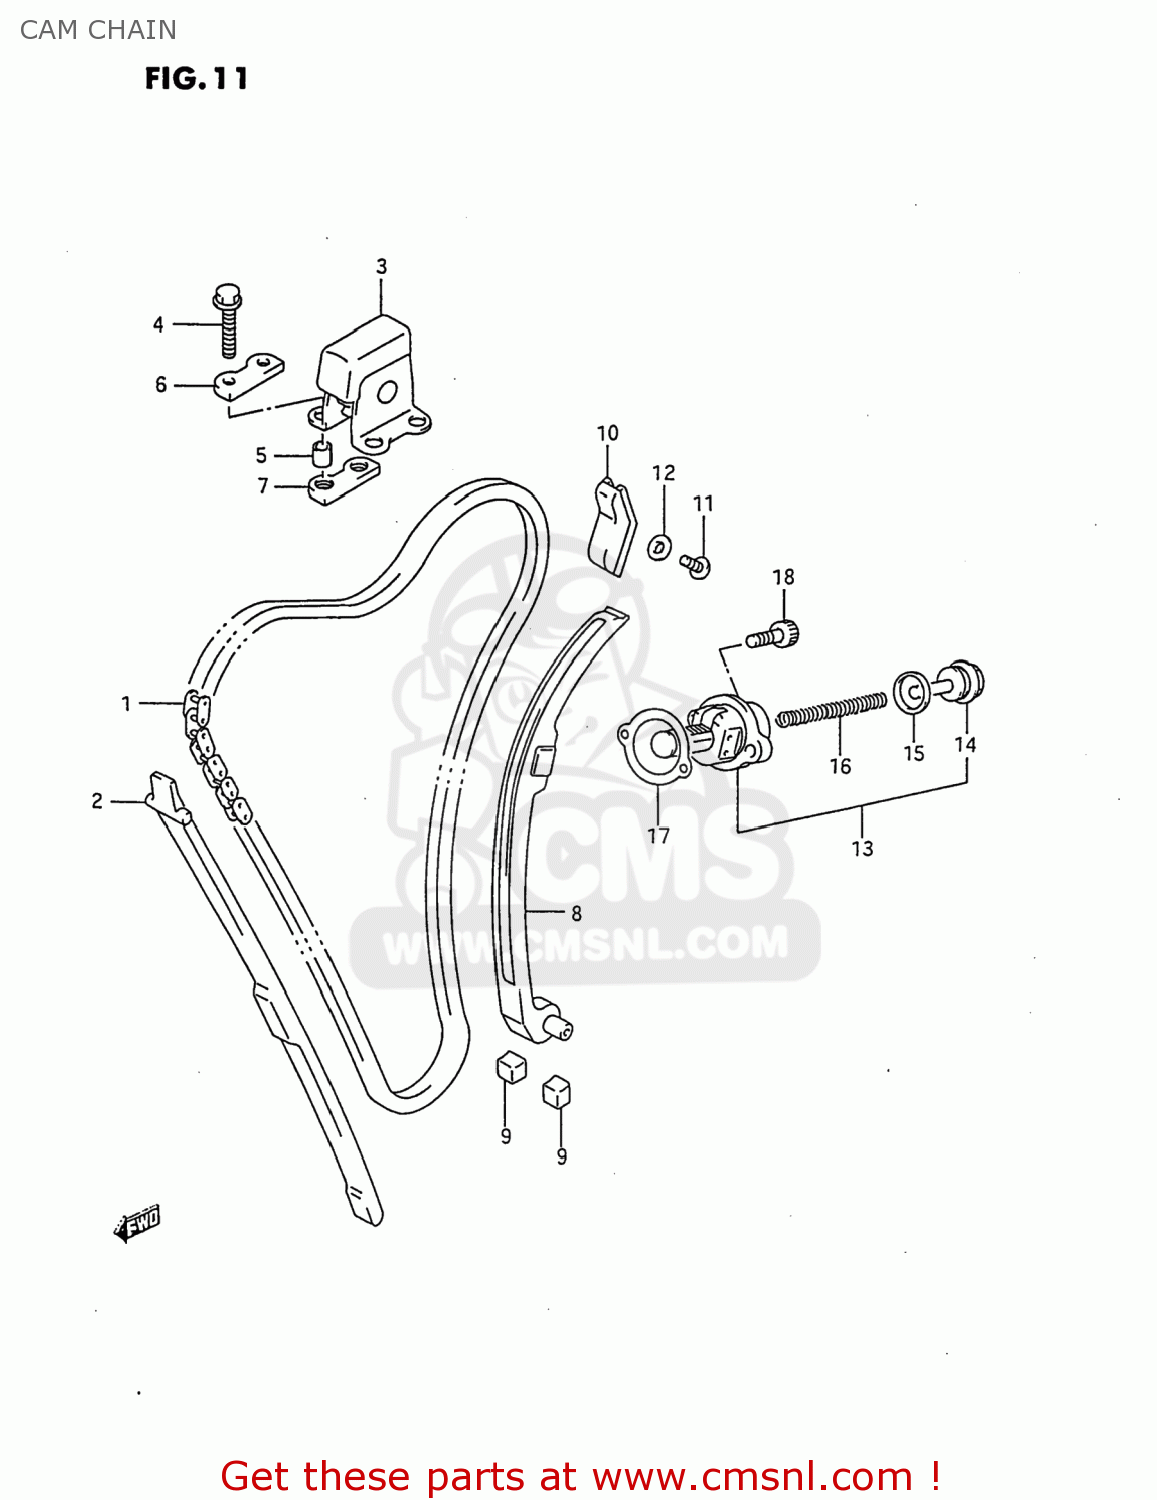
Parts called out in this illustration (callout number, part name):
1	CHAIN,CAMSHAFT DRIVE
2	GUIDE,CAM CHAIN NO.1
3	IDLER,CAM CHAIN
4	BOLT
5	SPACER (6.5X10X9.4)
6	CUSION,IDLER
7	CUSHION,IDLER
8	TENSIONER,CAM CHAIN
9	CUSHION,CAM CHAIN TENSIONER
10	GUIDE,CAM CHAIN NO.2
11	SCREW 6X10
12	GASKET(5.8X13X1.2) (NAS)
13	ADJUSTER ASSY,TENSIONER
14	PLUG
15	GASKET (NAS)
16	SPRING
17	GASKET,TENSIONER ADJUSTER (NAS)
18	BOLT,CL.COVER
